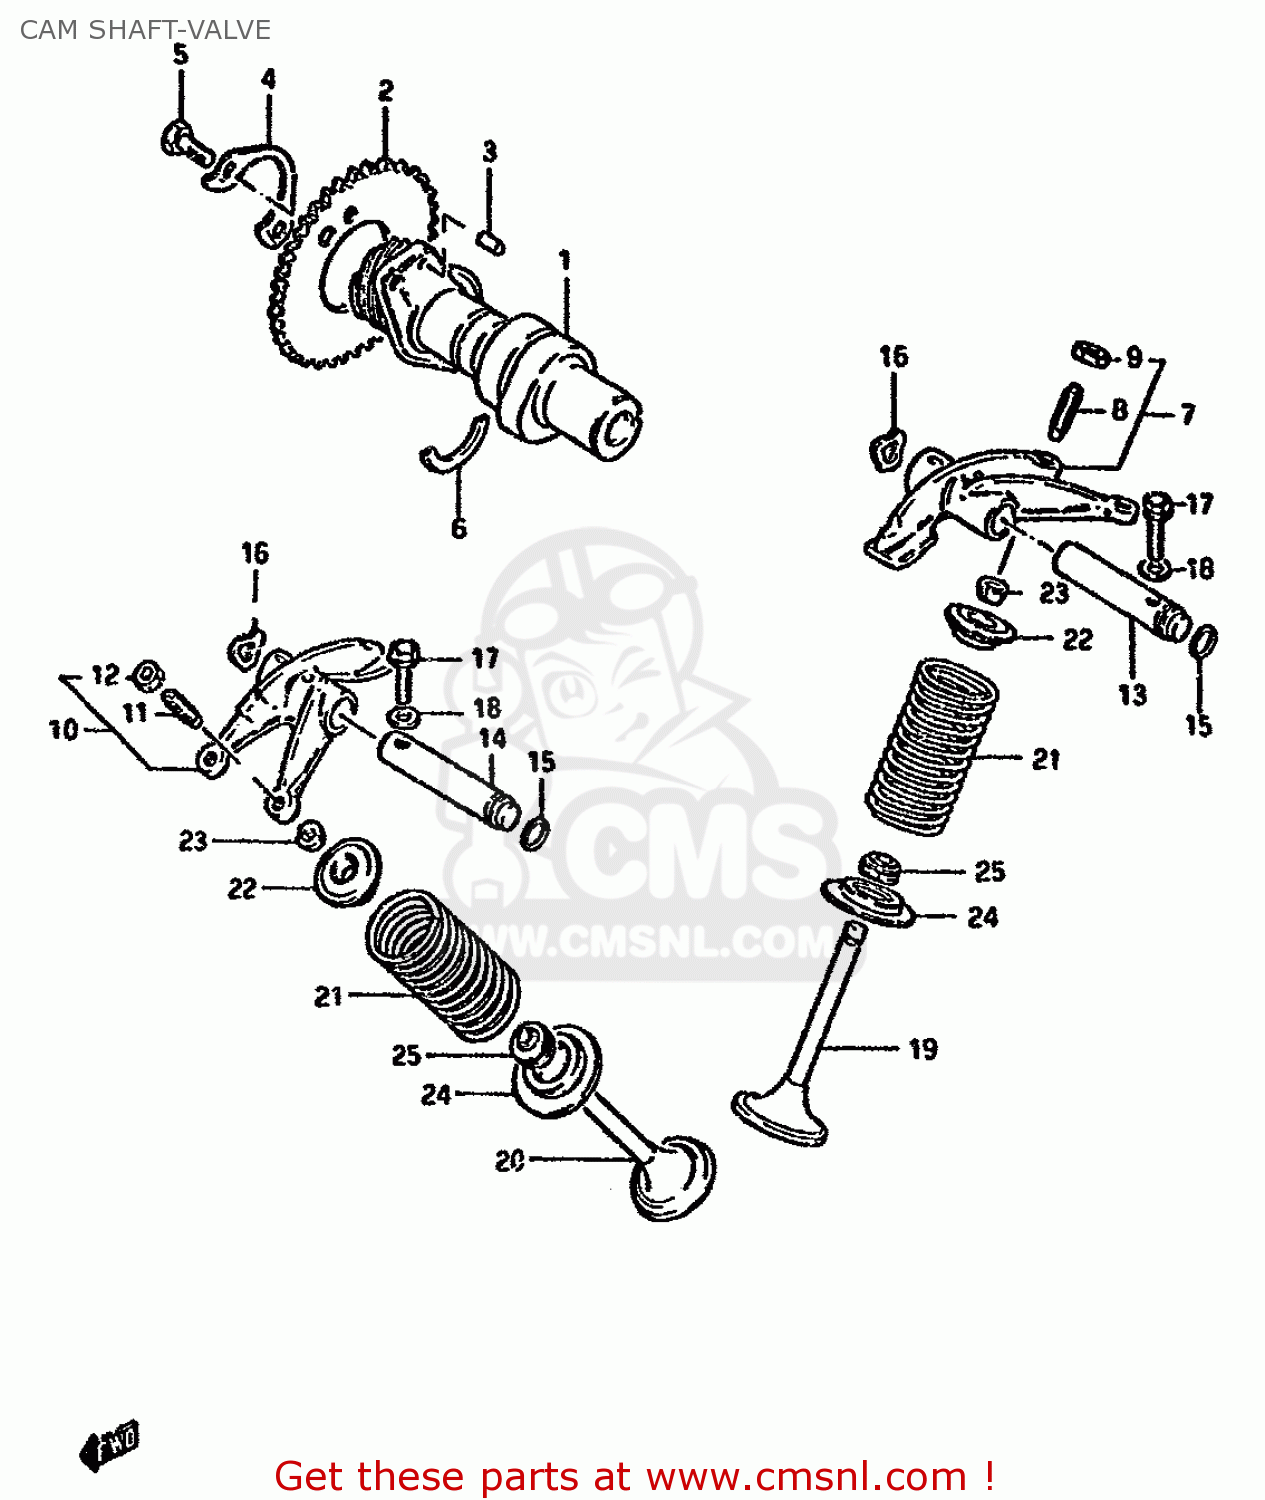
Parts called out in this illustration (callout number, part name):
1	CAMSHAFT
2	SPROCKET,CAMSHAFT(NT:42)
3	PIN
4	WASHER,CAM CHAIN SPROCKET
5	BOLT(6X12.5)
6	C RING
7	ARM,VALVE ROCKER INTAKE
8	SCREW,TAPPET ADJUSTING
9	NUT,ADJUSTING
10	ARM,VALVE ROCKER EXHAUST
11	SCREW,TAPPET ADJUSTING
12	NUT,ADJUSTING
13	SHAFT,VLV ROCKER ARM IN(L:91.5
14	SHAFT,VLV ROCKER ARM EXH(L:76)
15	O RING(D:1.9,ID:8.6)
16	WASHER
17	BOLT
18	GASKET(5.8X13X1.2) (NAS)
19	VALVE,INTAKE
20	VALVE,EXHAUST
21	SPRING,VALVE
22	RETAINER,VALVE SPRING
23	COTTER VALVE
24	SEAT,VALVE SPRING
25	SEAL,OIL(5.5X11X8.2)
